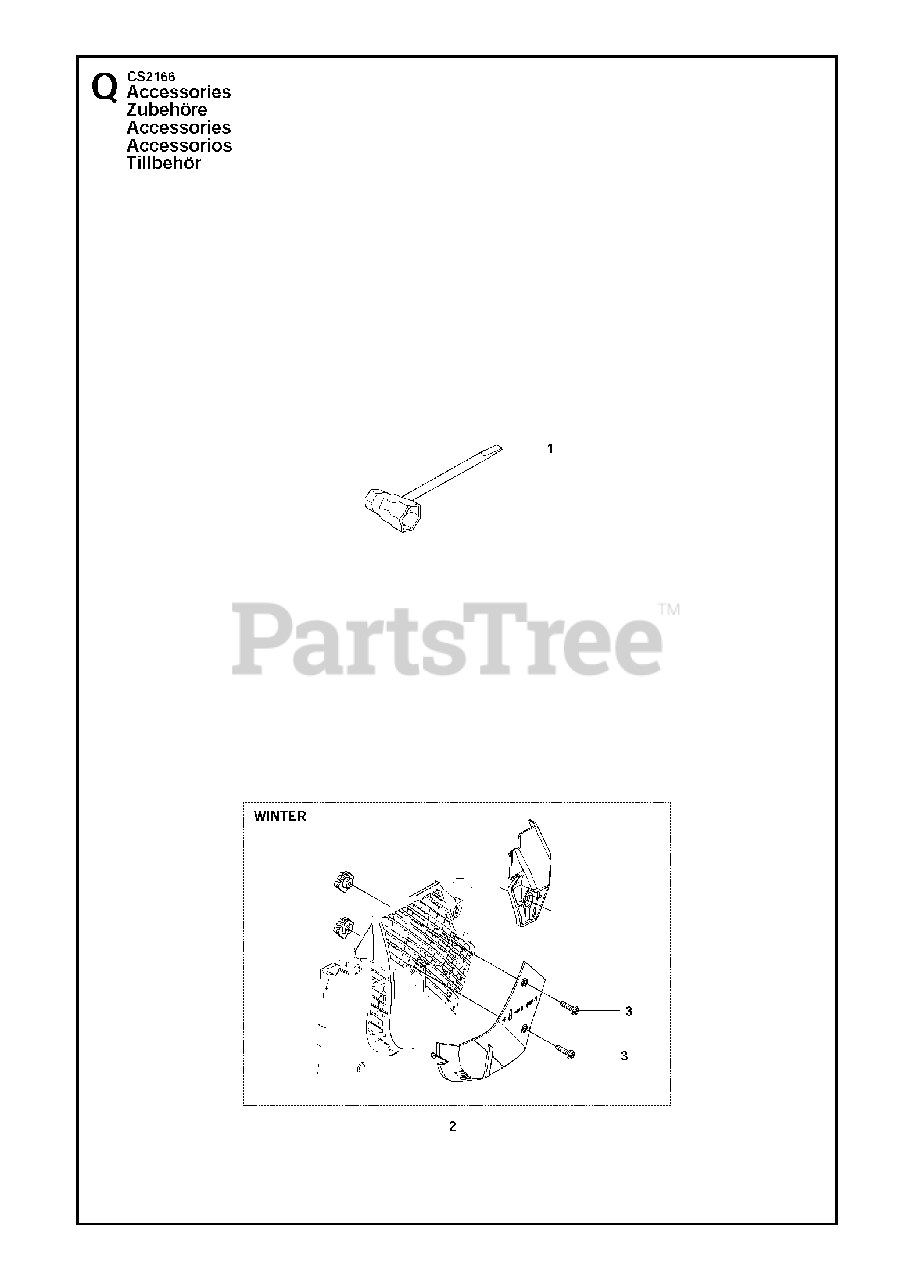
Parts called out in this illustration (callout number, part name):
1	COMBI TOOL
2	KIT
3	SCREW
